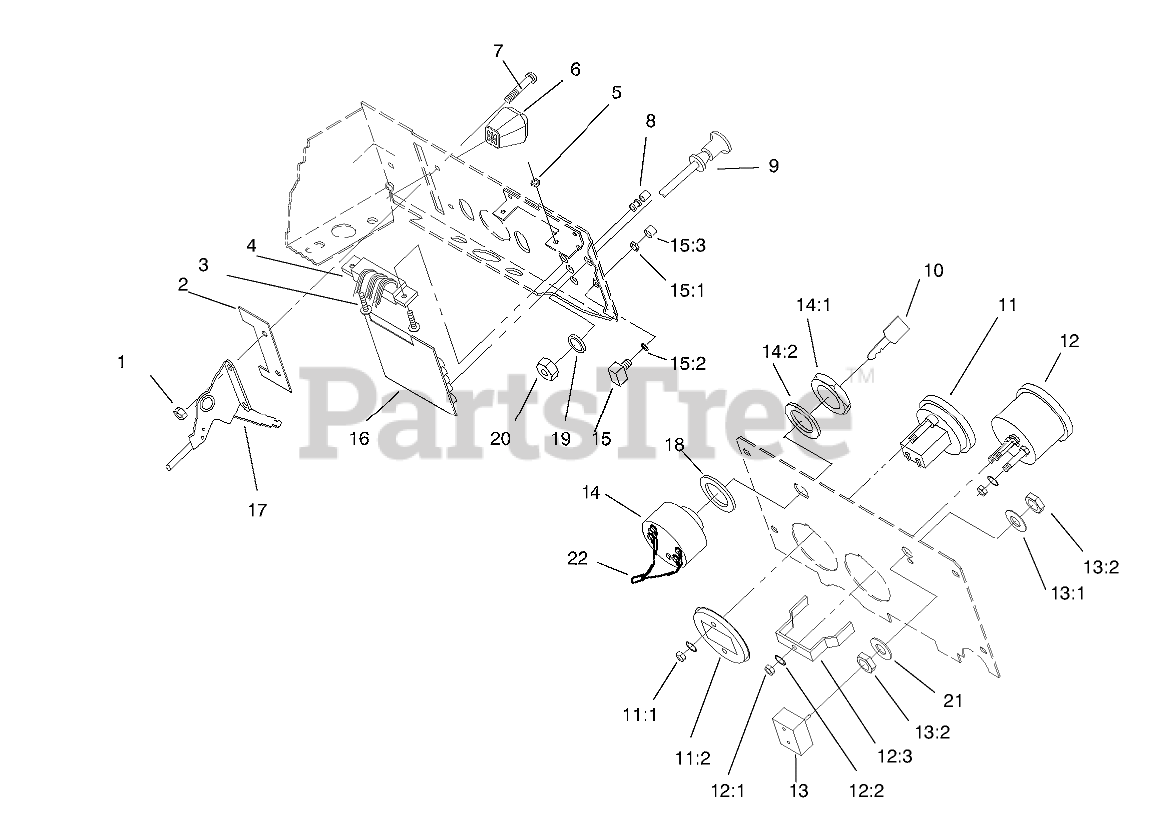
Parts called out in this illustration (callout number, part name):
1	Nut
2	STOP-THROTTLE
3	Screw
4	P.C.-BOARD HARNESS
5	NUT-HEX
7	SCRW-PHC
8	ASSY LENS & BUSHING
9	CONTROL CHOKE
10	KEY-IGNITION
11	Hourmeter
11:1	NUT-HEX, KEPS
11:2	Retainer
12	VOLTMETER
12:1	CLAMP-MOUNTING
12:2	WASHER-LOCK / EXT
12:3	NUT-HEX
13	SWITCH-LIGHTS
13:1	WASHER-LOCK
14	KEY SWITCH ASM
14:2	Washer-Lock
15	SWITCH-PUSH BUTTON
15:1	NUT F/W 116796
15:2	Washer
15:3	ASSY-TUBE SUCTION
16	Board-Pc
17	CONTROL-THROTTLE
18	WASHER
19	WASHER-FLAT
20	NUT-HEX PALNUT
21	WASHER
22	WIRING HARNESS & DIA
